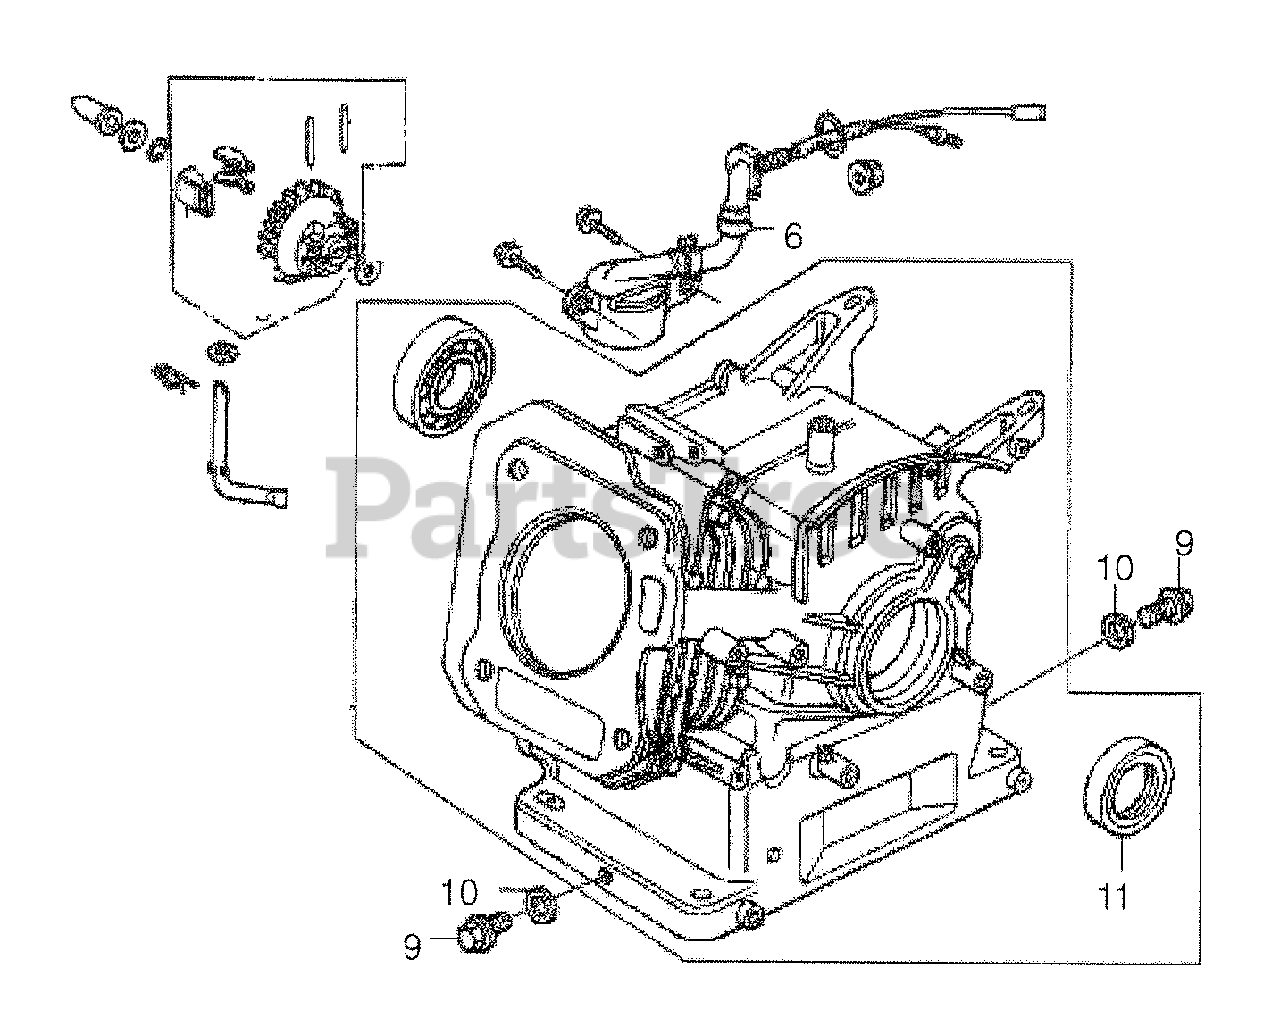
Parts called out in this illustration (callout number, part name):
6	SWITCH ASSY,OIL LEVEL
9	BOLT, DRAIN PLUG, 10 X 15
10	WASHER, DRAIN PLUG, 10.2MM
11	OIL SEAL 25X41.25X6
